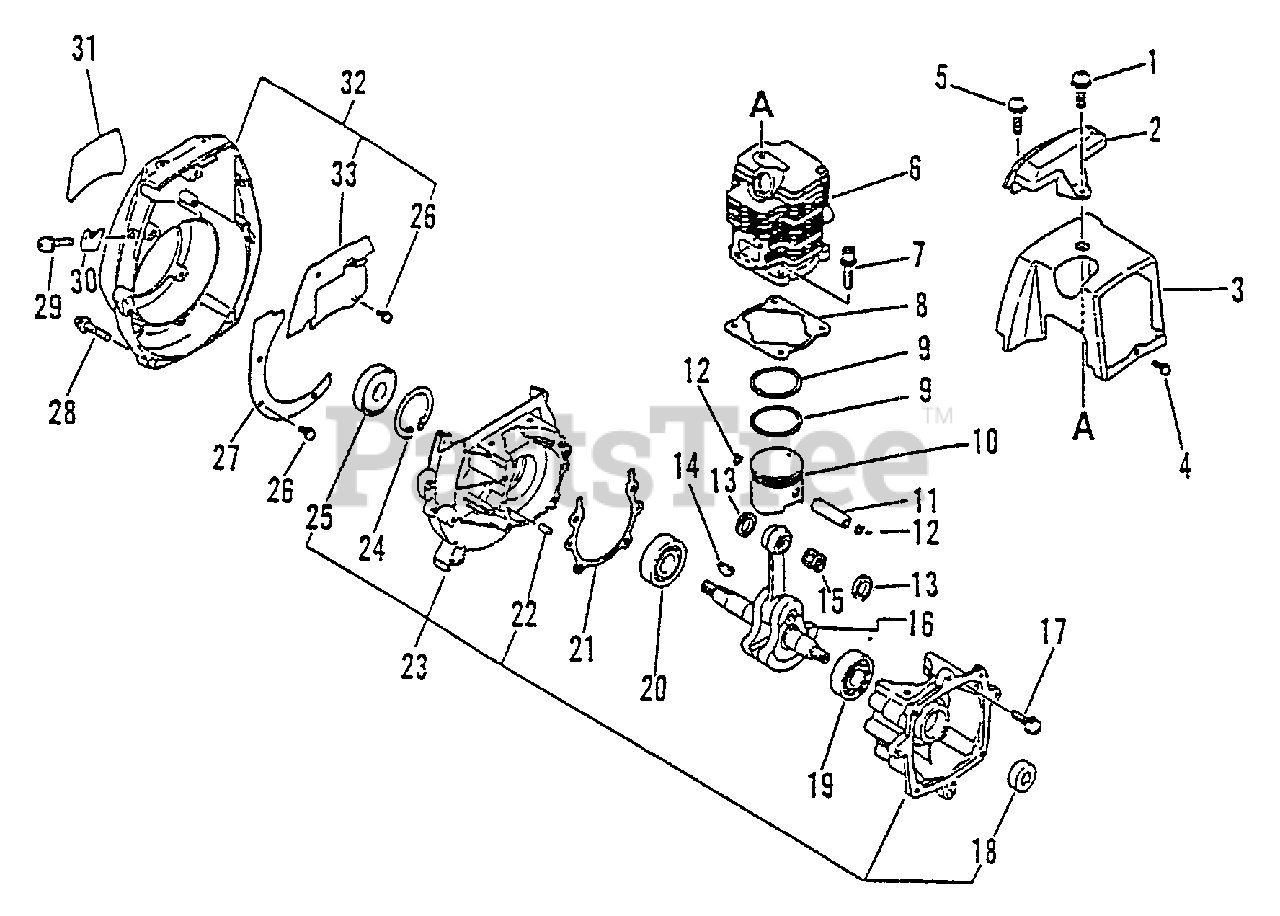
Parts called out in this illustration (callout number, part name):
1	SCREW - 5X16
2	GUARD - TOP
3	COVER, ENGINE
4	SCREW - 4X10
5	SCREW - 4X14
6	CYLINDER
7	SCREW - 5X20
8	GASKET, CYLINDER
9	RING, PISTON
10	PISTON KIT
11	PIN, PISTON
12	RING, RETAINING
13	SPACER, PISTON
15	BEARING, NEEDLE
16	CRANKSHAFT ASSY
17	SCREW - 5X25
18	SEAL, OIL
19	BEARING, BALL - 6001C3
20	BEARING, BALL - 6201
21	GASKET, CRANKCASE
22	PIN - LOCATING
23	CRANKCASE KIT
24	RING, RETAINING - 32
25	SEAL, OIL
26	SCREW - 4X8
27	SHIELD, FAN
28	SCREW - 5X20
29	SCREW - 4X10
30	HOLDER, CABLE
31	LABEL - MODEL
32	FAN CASE ASSY
33	SHIELD, FAN
